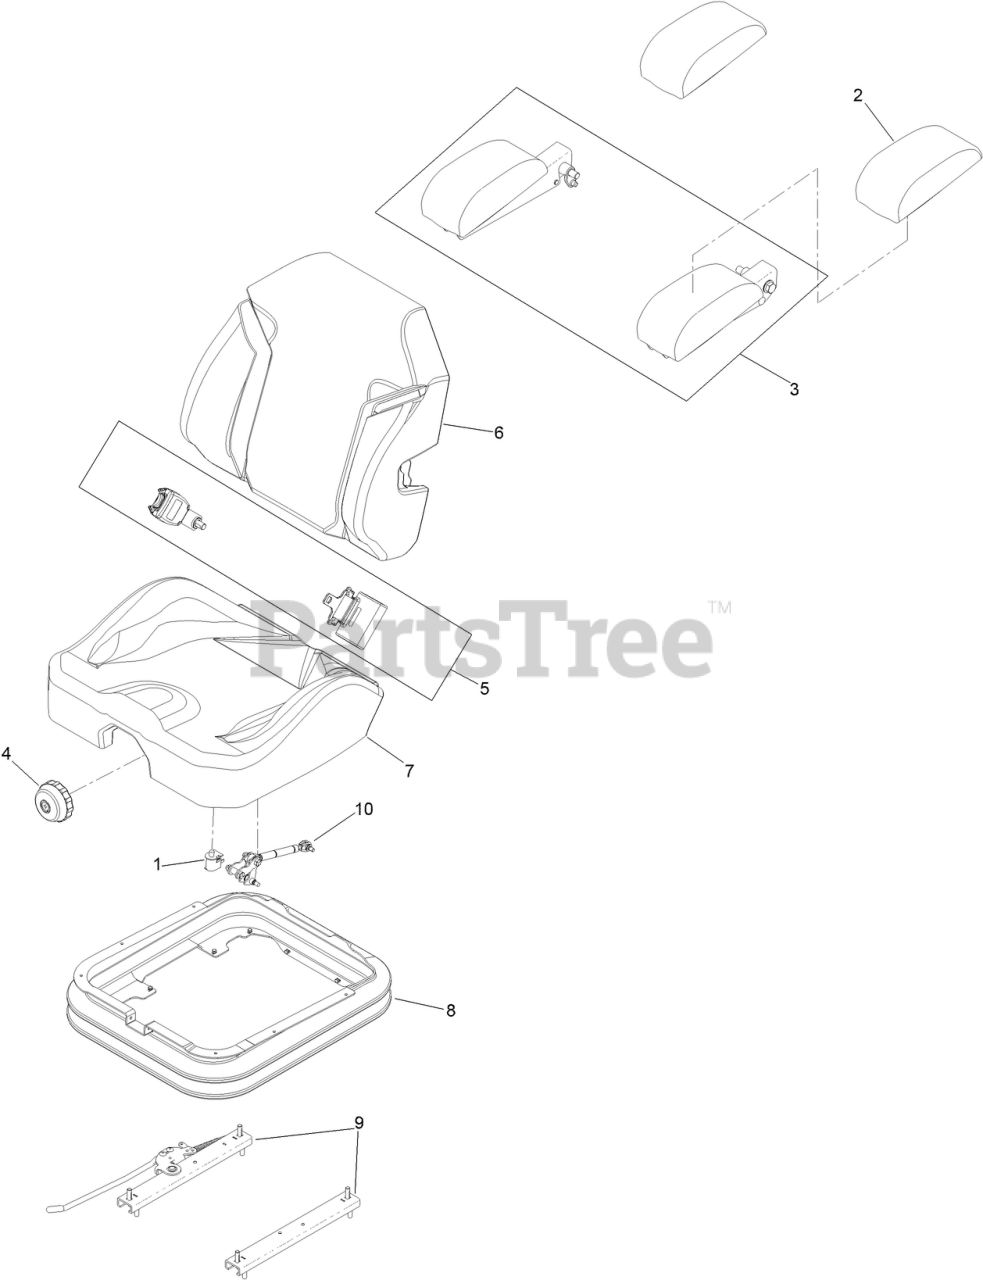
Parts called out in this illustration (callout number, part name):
1	SWITCH-BAIL
2	KIT-ARM REST PADS
3	KIT-ARM REST SET
4	KNOB-ADJUSTER
5	KIT-SEAT BELT
6	COVER-BACK
7	COVER-CUSHION
8	COVER-SUSPENSION BELLOWS
9	SET-SEAT TRACK
10	DAMPER-SEAT
